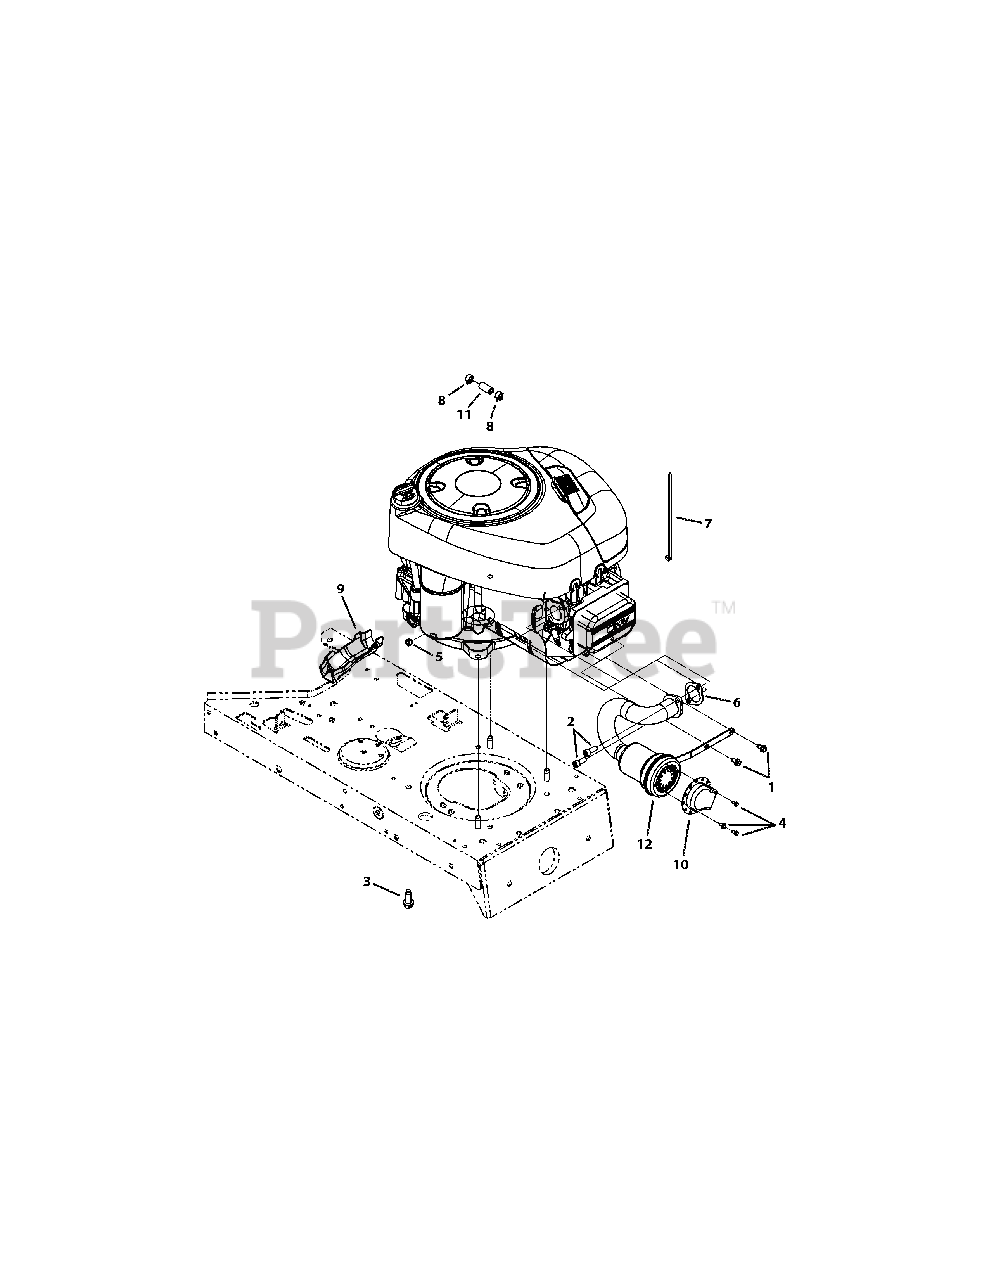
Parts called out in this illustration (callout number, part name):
1	Screw, 1/4-20 x .500
2	Socket Screw, 5/16-18 x .750
3	Screw, 3/8-16 x 1.000
4	Screw, 8-18 x .500
5	Sems Nut, 1/4-20
6	Exhaust Gasket, 10 HP Briggs
7	Cable Tie
8	Hose Clamp, .490 Diameter
9	Oil Drain Sleeve
10	Muffler Deflector
11	Fuel Hose, Low Permeation
12	Muffler
